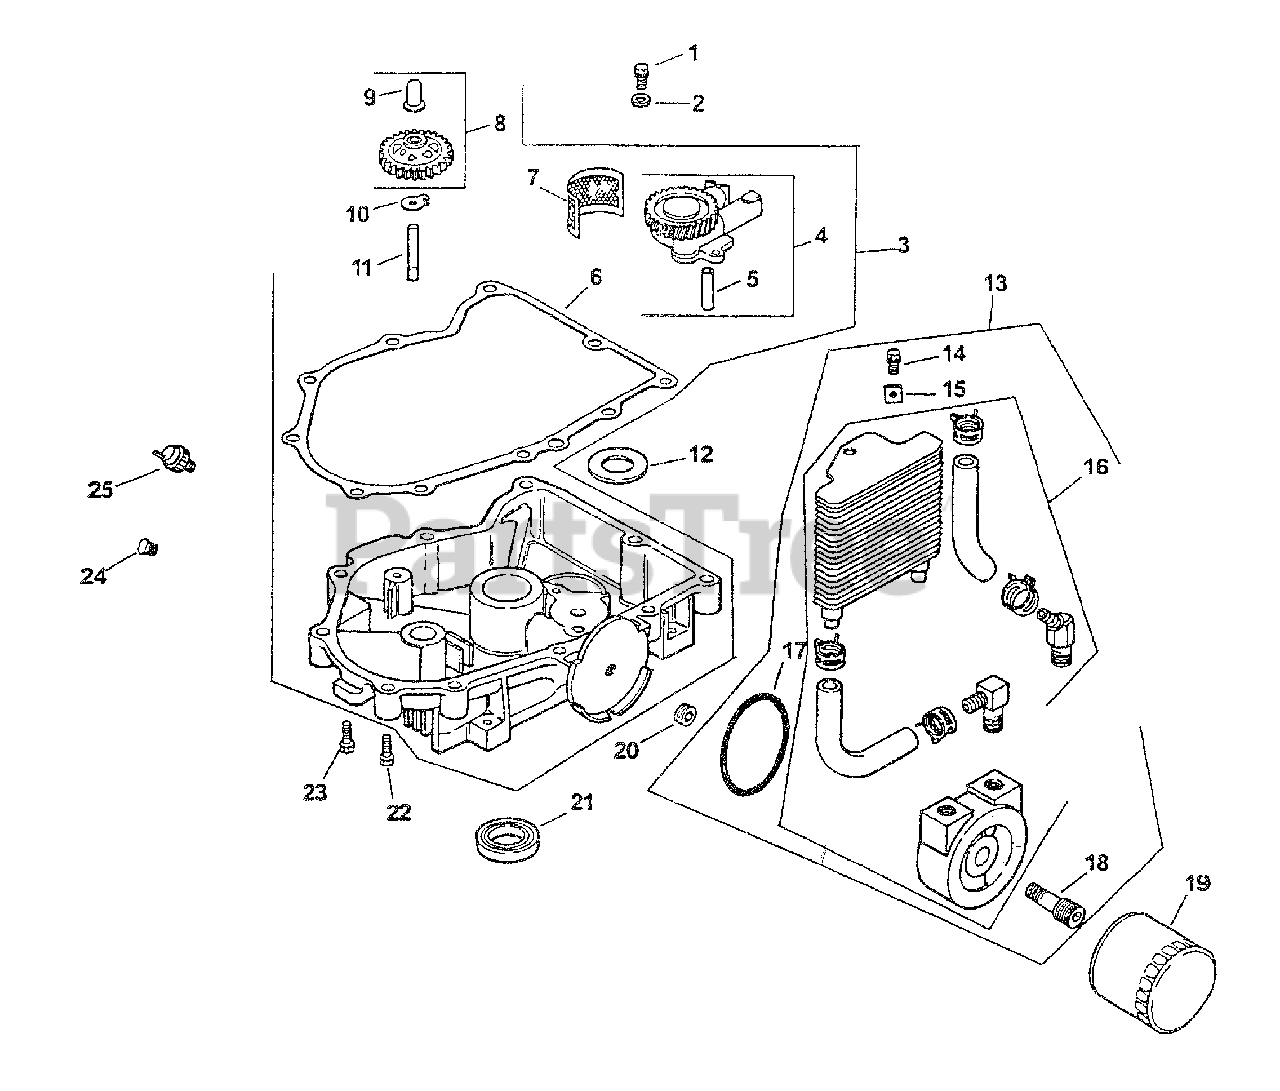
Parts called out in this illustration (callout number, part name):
1	Screw, Hex Flange
2	Washer, Plain 6mm
3	Kit, Oil Pan w/Gaskets
4	Oil Pump Assembly
5	Tube, Oil Pickup
6	Gasket, Oil Pan
8	Kit, Governor Gear
9	Pin, Governor Regulating
10	Tab, Locking
11	Shaft, Governor Gear
13	Kit, Oil Cooler
14	Screw, Hex Cap
15	Nut, Plastic
16	Oil Cooler - Phenolic
17	O-Ring
18	Nipple, Oil Filter
19	Filter, Oil
20	Plug, Hex 3/8"
21	Seal, Oil (P.T.O. End)
22	Screw, Hex Flange
23	Screw, Hex Flange
24	Plug, Hex Head 3/8"
25	Switch, Oil Pressure
